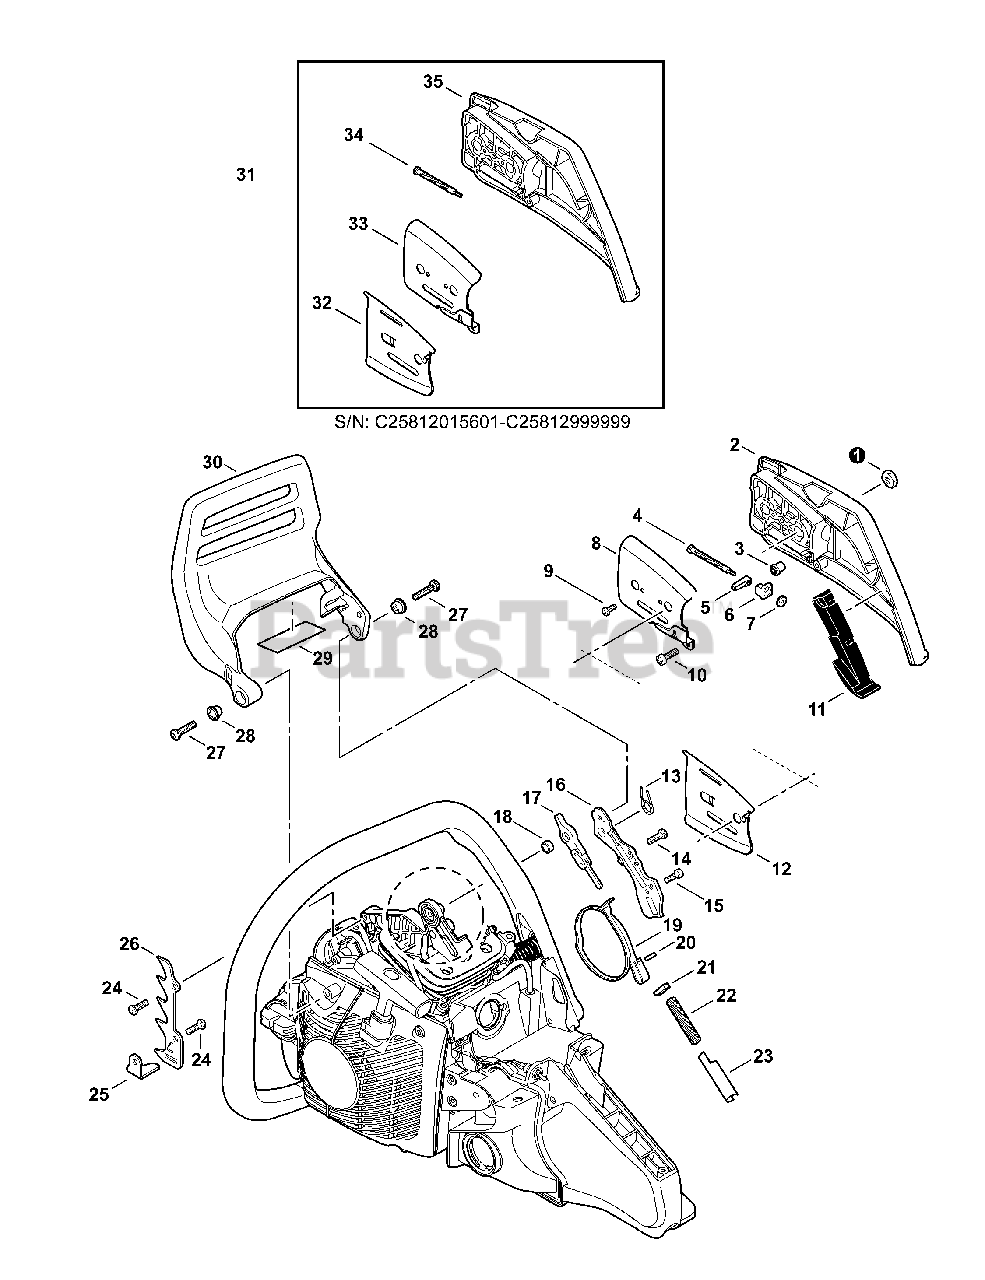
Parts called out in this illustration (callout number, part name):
1	NUT - 8
2	GUARD, SPROCKET
3	GEAR, PINION
4	SCREW, TENSIONER
5	TENSIONER, CHAIN
6	COLLAR - 8
7	GEAR, BEVEL
8	PLATE, GUIDE - OUTER
9	SCREW - 3×6
10	SCREW - 4×12
11	CUSHION
12	PLATE, GUIDE - INNER
14	SCREW - 5×16
15	SCREW - 4×12
16	COVER, BRAKE
17	CONNECTOR, BRAKE
19	BAND, BRAKE
20	PIN, SPRING
23	GUIDE, SPRING
24	SCREW - 5×16
25	CATCHER, CHAIN
26	BUMPER, SPIKED
27	SCREW - 5×16
29	DEFLECTOR, HEAT
30	LEVER, BRAKE
31	SPROCKET GUARD KIT
32	PLATE, GUIDE - INNER
33	PLATE, GUIDE - OUTER
34	SCREW, TENSIONER
35	GUARD, SPROCKET
